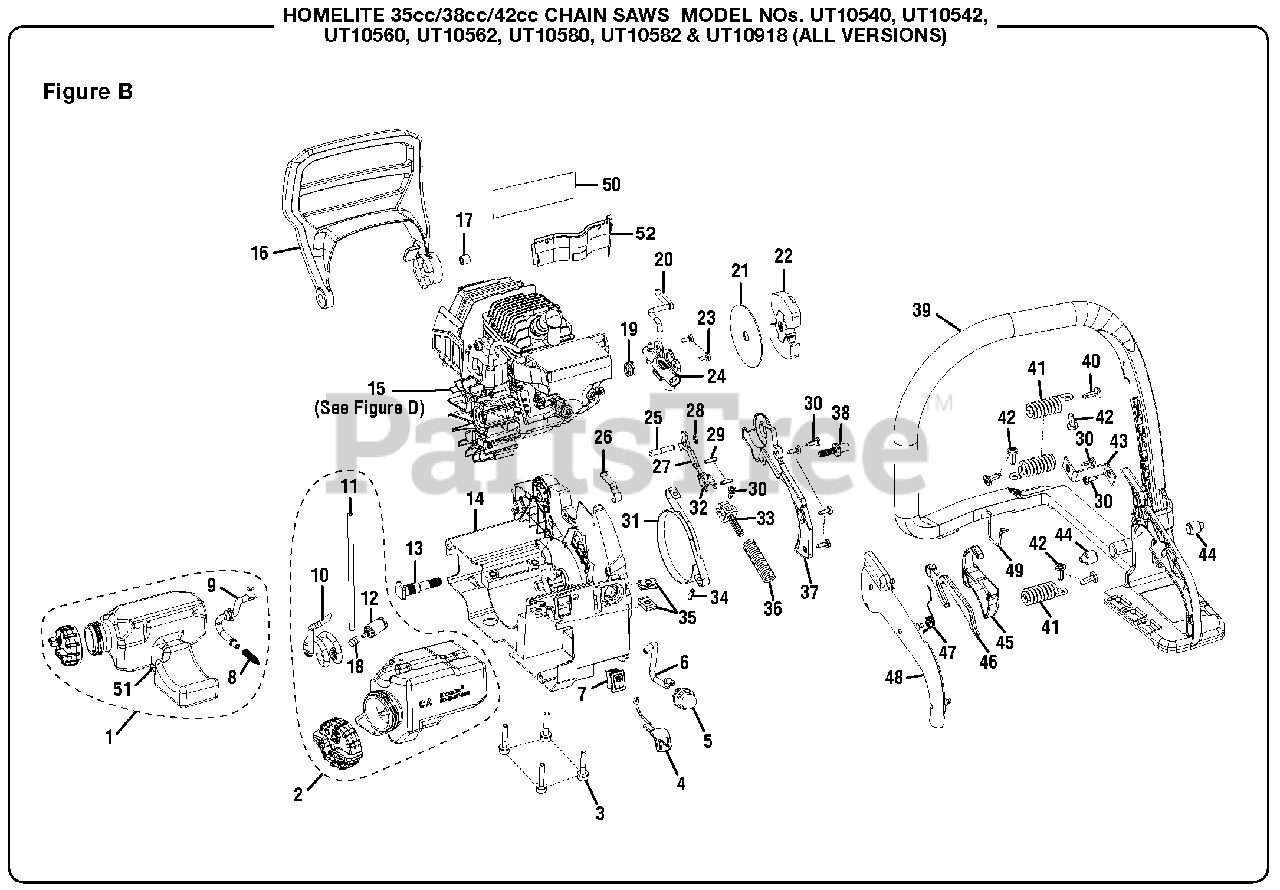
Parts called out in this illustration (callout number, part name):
1	Oil Tank & Cap Assembly
2	Fuel Tank & Cap Assembly
3	Screw (M5 x 28 mm)
4	Choke Lever
5	Primer Bulb
6	Primer Bulb Inlet Tube (73 mm)
8	Cone Spring
9	Oil Pump Inlet Tube
10	Fuel Line Inlet (205 mm)
11	Fuel Line (105 mm)
12	Fuel Filter
13	Guide Bar Bolt (M8 x 42.3 mm)
14	Main Chassis
15	Engine Assembly
16	Front Hand Guard
17	Hand Guard Insert
18	Hose Clamp
19	Oil Pump Gear Spring
20	Oil Pump Outlet Tube
21	Thrust Washer
22	Clutch Assembly
23	Screw (M4 x 9.5 mm)
24	Oil Pump Assembly
25	Chain Brake Pin
27	Chain Break Pivot
28	E-Ring
29	Spring Pin
30	Screw (M4 x 12 mm)
31	Brake Band
32	Chain Brake Linkage
33	Spring Guide
34	Spring Pin
35	Speed Nut ("U"-Type)
36	Chain Brake Spring
37	Chain Brake Cover
38	Bar Bushing
39	Rear Handle
40	Screw (10-24 x 5/8 in.)
41	Isolator Spring
42	Screw (10-14 x 16 mm)
43	Anti-Vibe Strap
46	Lock-Out Lever
47	Trigger Return Spring
48	Rear Handle Cover
49	Throttle Rod
50	Heat Shield
52	Heat Dam Adapter
